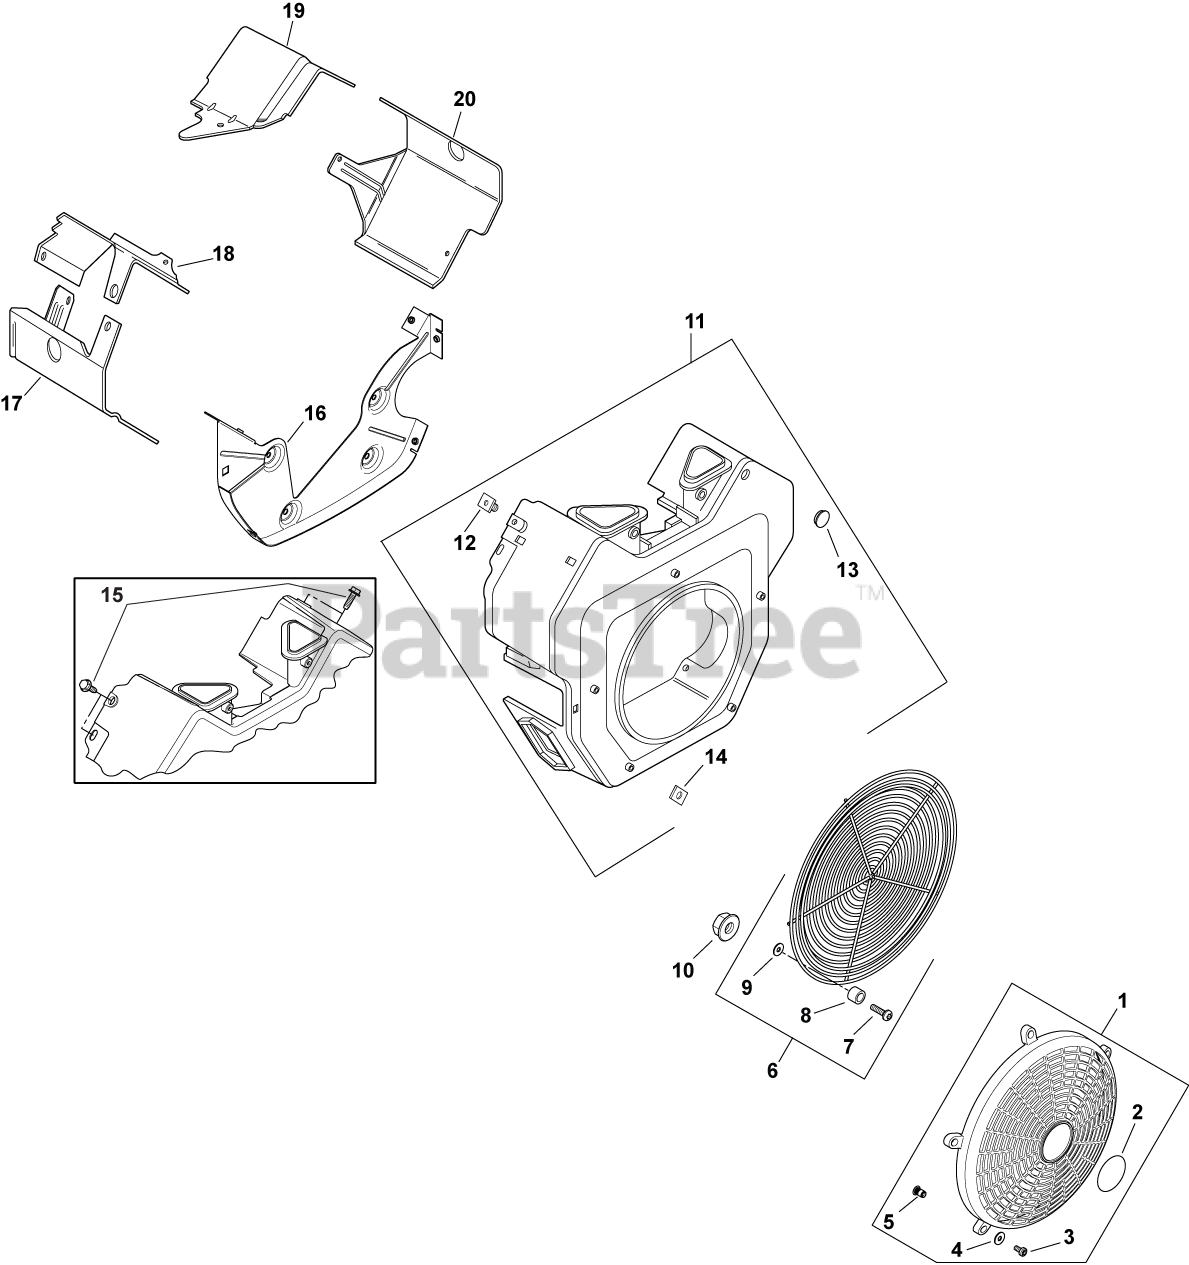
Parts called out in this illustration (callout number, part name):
1	KIT, FIXED GUARD
2	DECAL, GRASS SCREEN USE 24 113 499-S
3	SCREW, SEMS
4	WASHER, FLAT 7/32"
5	INSERT, THREADED USE 25 332 19-S
6	KIT, GRASS SCREEN GUARD
7	SCREW, SPECIAL HEAD
9	WASHER, FLAT 1/4" (O.D. 5/8")
11	KIT, BLOWER HOUSING ASSEMBLY USE 24 027 477-S
12	NUT, PLASTIC (KM)-USE 25 100 37-S
13	PLUG, BUTTON 9/16
14	NUT, PLASTIC
15	SCREW,FLG THD FRM M6X1.0X16-(#25086397S)
16	PLATE, BACKING-USE 24 146 59-S
18	BAFFLE,VALLEY #2SIDE(KM)-USE 24 063 70-S
19	BAFFLE, VALLEY (CH)-USE 24 063 93-S
20	BAFFLE, RIGHT BARREL-USE 24 063 85-S
